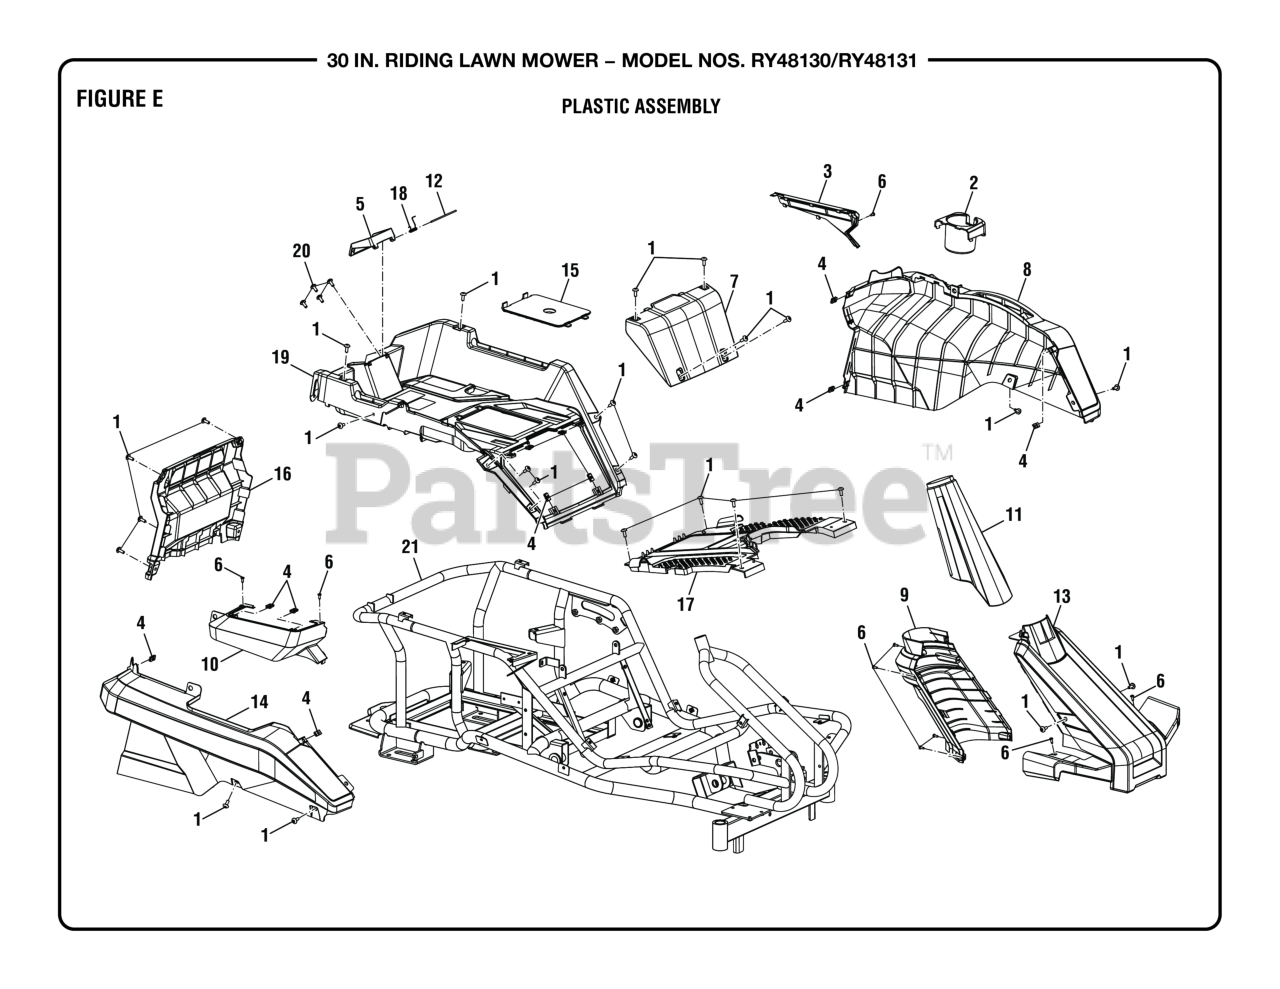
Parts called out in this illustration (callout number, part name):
1	Screw (M6 x 10 mm, Soc. Button Hd.)
2	Cup Holder
3	Rear Console Panel
4	Clip-On Nut (M6)
5	Charging Port Door
6	Screw (ST4.2 x 13 mm)
7	Front Access Panel
8	Left Trim Cover
9	Rear Steering Column Cover
10	Front Console Panel
11	Upper Steering Column Cover
12	Charger Port Door Hinge Pin
13	Front Steering Column Cover
14	Right Trim Cover
15	Top Access Panel
16	Rear Trim Cover
17	Floor Panel
18	Charger Port Door Spring
19	Center Trim Cover
20	Screw (M6.3 x 19 mm, Pan Hd.)
